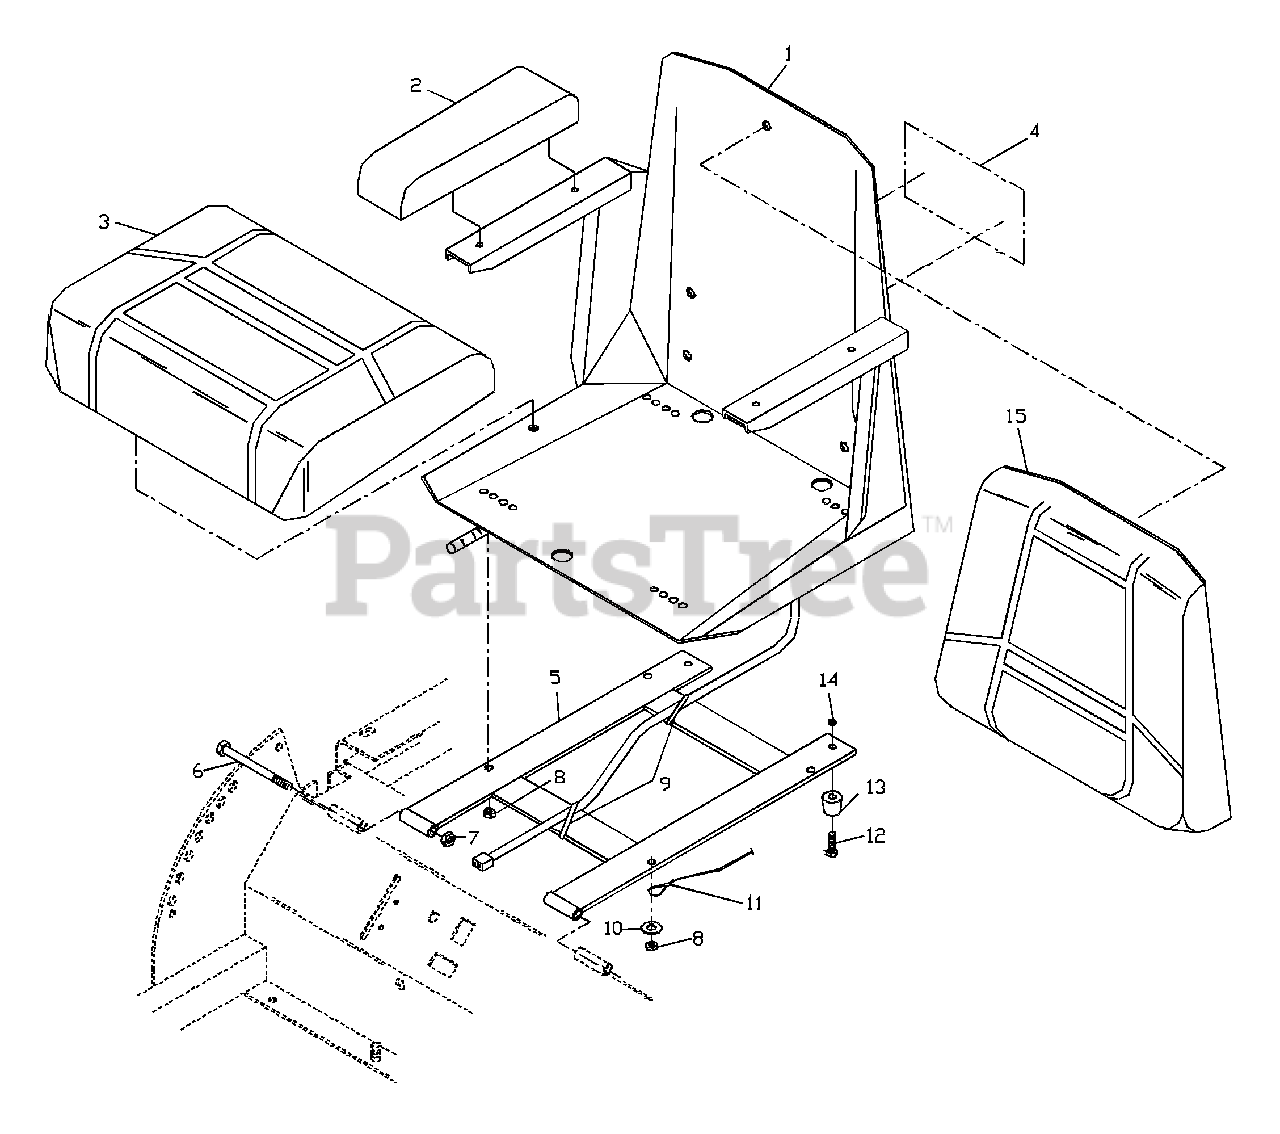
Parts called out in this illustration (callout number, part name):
1	COMPLETE-SEAT
2	ARM REST CUSHION
3	SEAT CUSHION W/SWITCH
4	DECAL, CROWN
5	SEAT MOUNT
6	HCS 3/8C X 4 1/2
7	NUT 3/8C CENTERLOCK
8	NUT 5/16C CENTERLOCK
9	PLASTIC TIE
10	5/16 FLAT WASHER
11	SEAT LANYARD
12	#10-24 X 1/2 SLOTTED SCREW
13	SEAT BUMPER
14	#10-24 NYLOC NUT
15	SEAT BACK CUSHION
